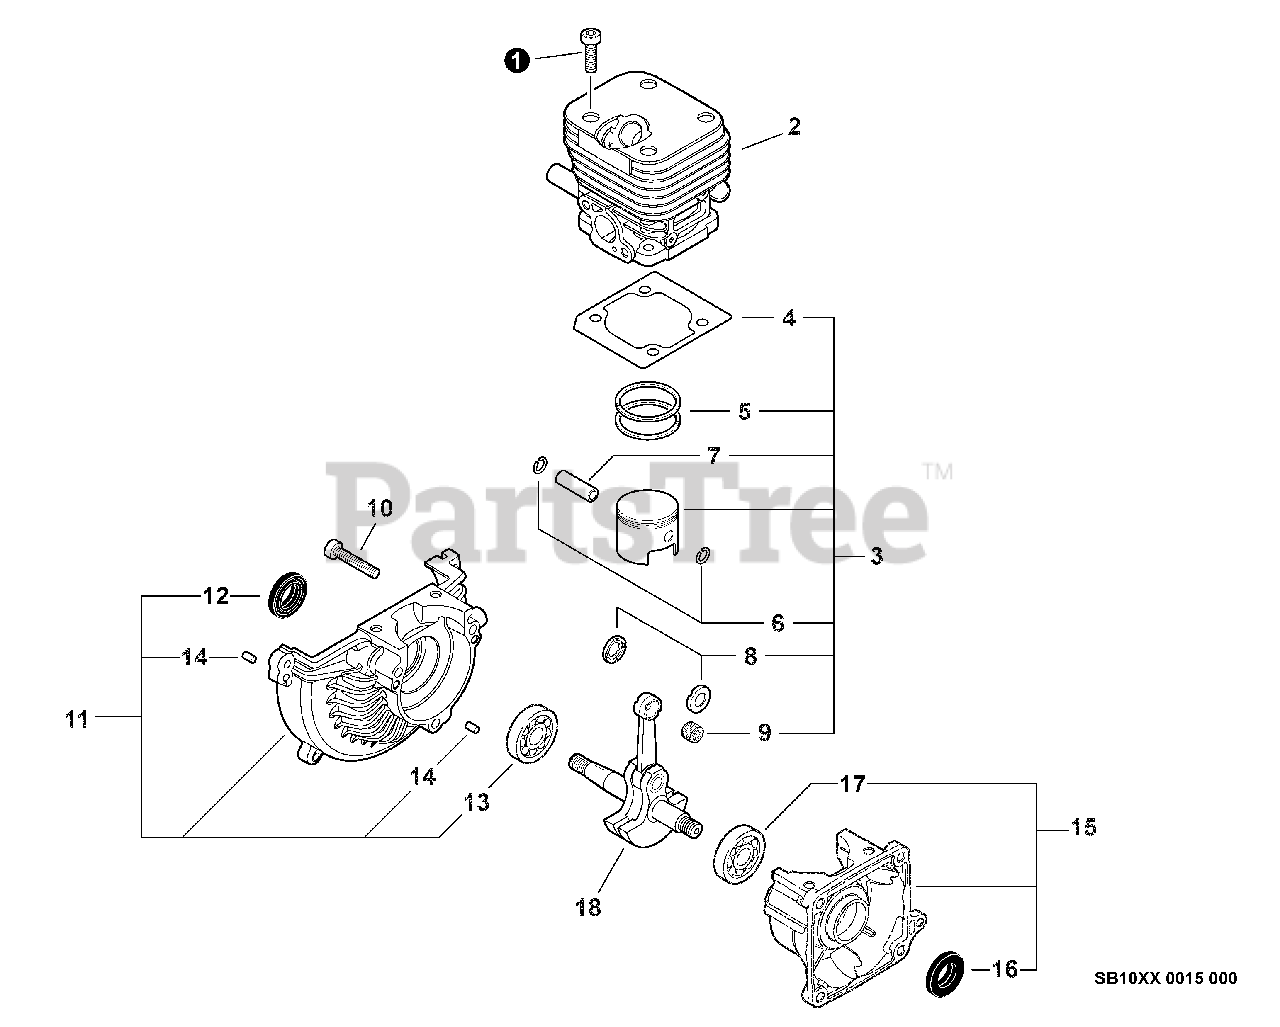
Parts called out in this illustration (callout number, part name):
1	SCREW - 5X16
2	CYLINDER
3	PISTON KIT
4	GASKET, CYLINDER
5	RING, PISTON
6	RING, RETAINING
7	PIN, PISTON
8	SPACER - 9
9	BEARING, NEEDLE
10	SCREW - 5X25
11	CRANKCASE ASSY - FRONT
12	SEAL, OIL
13	BEARING, BALL - 6001
14	PIN - LOCATING
15	CRANKCASE ASSY - REAR
16	SEAL, OIL
17	BEARING, BALL - 6001
18	CRANKSHAFT ASSY
